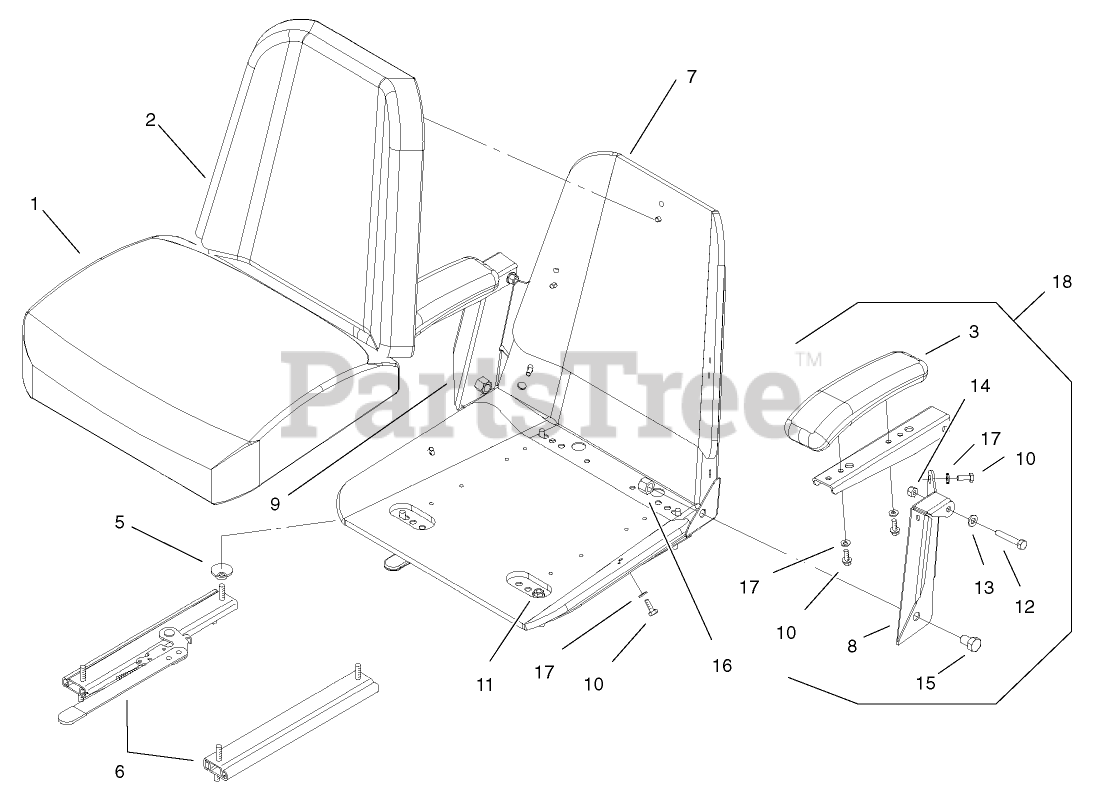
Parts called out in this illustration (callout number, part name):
1	CUSHION-SEAT, BOTTOM
2	CUSHION-SEAT, BACK
3	CUSHION-ARMREST
5	SPACER-TRACK
6	TRACK-SEAT
7	FRAME-SEAT
8	Bracket-Armrest, LH
9	Bracket-Armrest, RH
10	SCREW-HH
11	NUT-HF
12	SCREW-HH
13	WASHER-PLAIN
14	NUT-LOCK, NI
15	SCREW-HH
16	NUT-LOCK, NI
17	WASHER-FLAT
18	ARMREST KIT
